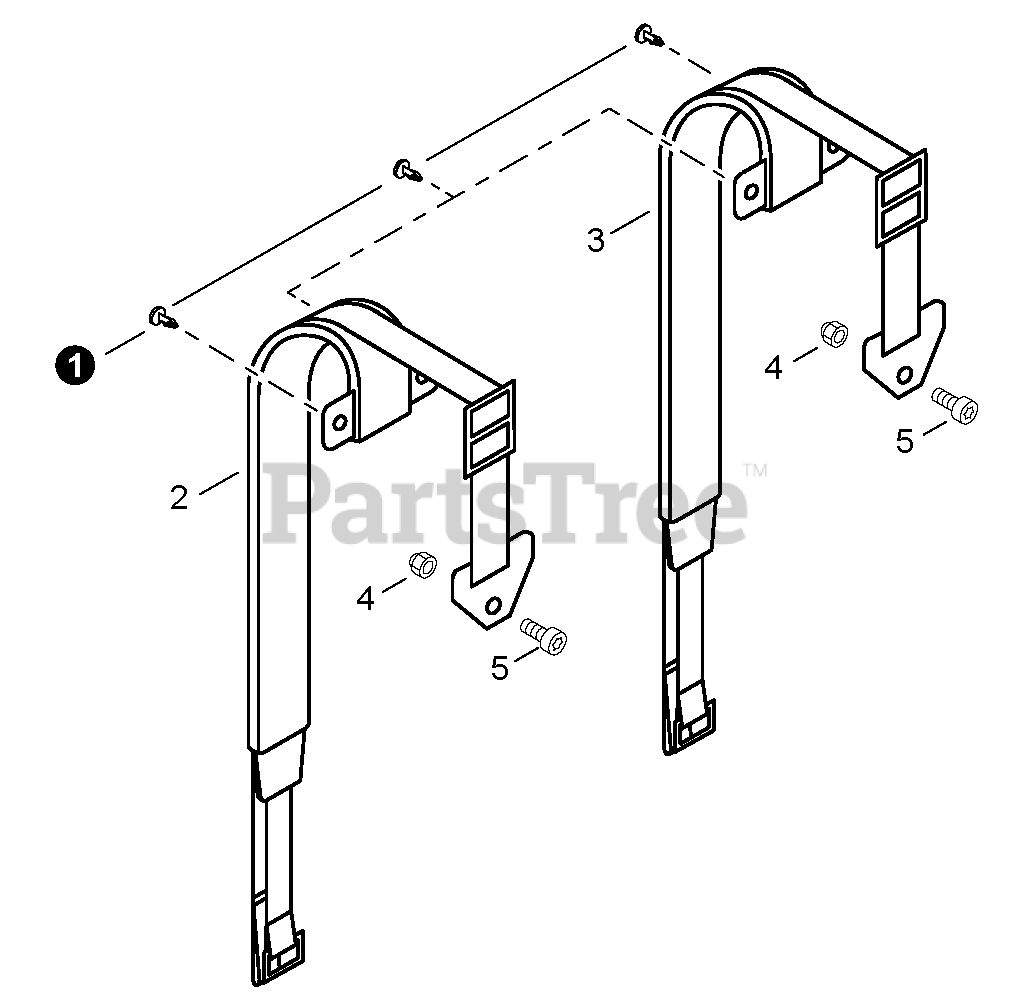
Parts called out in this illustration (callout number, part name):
2	BACKPACK STRAP ASSY - LEFT
3	BACKPACK STRAP ASSY - RIGHT
4	LOCKNUT - 5
5	SCREW - 5X30
